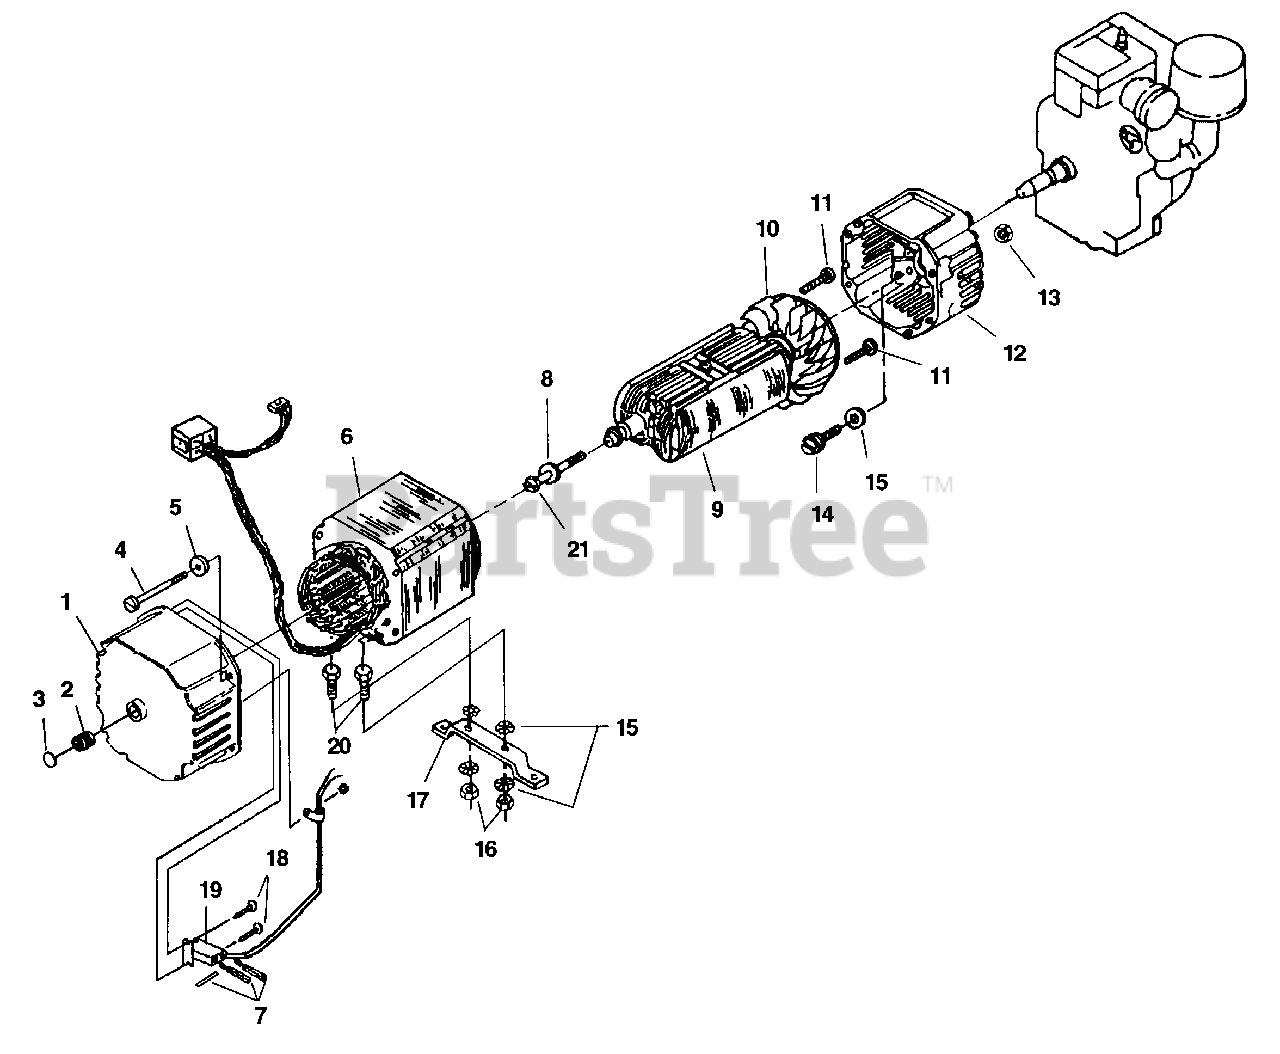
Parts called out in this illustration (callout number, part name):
1	Complete Brush Head
2	Bearing-Needle
3	Plug - Expansion
4	Bolt - Stator
5	Washer - Flat (1/4")
6	Stator & Harness
7	Brush & Retainer Kit
8	Washer - Lock (5/16")
10	Fan - Generator
11	Screw - Pan Hd. (6-19 X 3/4")
12	End Bell
13	Nut - Hex (1/4-20)
14	Screw - Hex Hd. (5/16-24 X 3/4")
15	Washer - Lock
16	Nut - Hex (5/16-18)
17	Bracket - Generator Support
18	Screw - Plastite (6-19 X 3/4")
19	Brush Holder
20	Screw - Hex Hd. (5/16-18 X 3/4")
21	Bolt - Rotor
